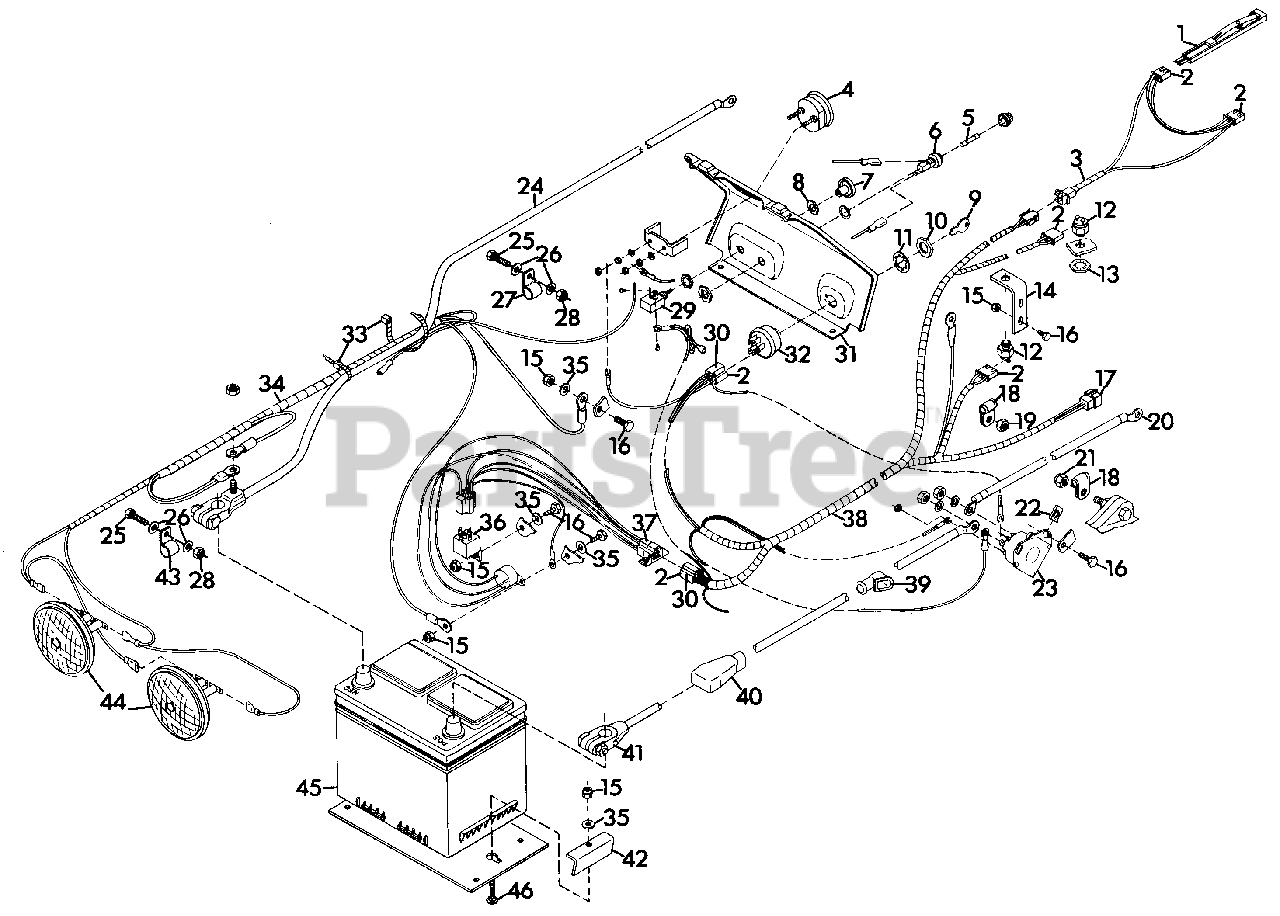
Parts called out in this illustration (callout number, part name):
1	SWITCH, SEAT
2	TERMINAL
3	HARNESS, WIRING SEAT SWITCH
4	GAUGE, AMMETER
5	FUSE, 30 AMP AGC 30
6	FUSE, PANEL
7	KNOB, LIGHT SWITCH
8	NUT, SPECIAL LIGHT SWITCH
9	KEY, IGNITION SWITCH
10	NUT, JAM 9/16-24
11	WASHER, LOCK INT. TOOTH
12	SWITCH, INTERLOCK
13	NUT, STAMPED 9/16-18
14	BRACKET, SWITCH
15	NUT, LOCK 1/4-20
16	BOLT, HEX 1/4-20X.75
17	CONNECTOR
18	CLAMP
19	NUT, LOCK 3/8-16
20	CABLE, STARTER
21	NUT, LOCK 3/8-16
22	NUT, SPEED 1/4-20
23	SWITCH, MAGNETIC
24	CABLE, NEGATIVE BATTERY
25	BOLT, HEX 5/16-18X1.00
26	WASHER, FLAT .344X.688X.065
27	CLAMP, NYLON
28	NUT, LOCK 5/16-18
29	SWITCH, LIGHT
30	CONNECTOR
31	PANEL, INSTRUMENT
32	SWITCH, IGNITION
33	TIE, CABLE
34	HARNESS, WIRING GROUND AND LIGHTS
35	WASHER, FLAT .281X.625X.065
36	RELAY
37	MODULE, TIME DELAY
38	HARNESS, WIRING
39	BOOT, BATTERY CABLE
40	COVER, BATTERY TERMINAL
41	CABLE, BATTERY TO MAGNETIC SWITCH
42	CLAMP
43	CLAMP, NYLON
44	HEADLIGHT
45	BATTERY, 12 VOLT
46	BOLT, 1/4-20X1.75 RD HD SQ NK
